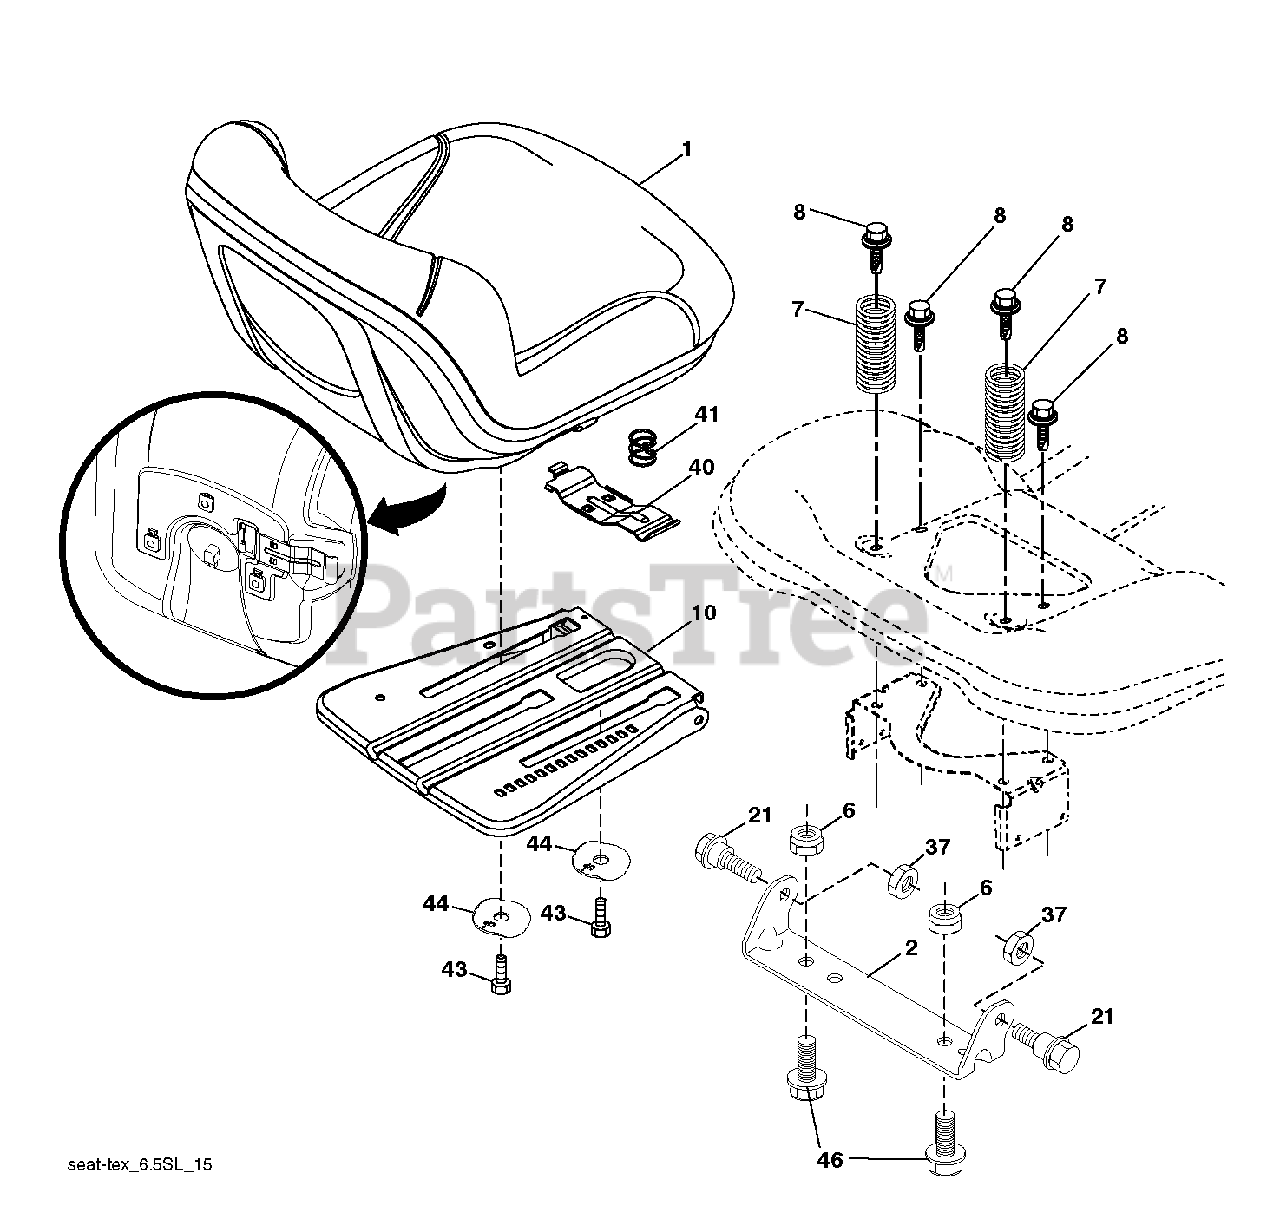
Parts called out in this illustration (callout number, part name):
1	SEAT.TH150.MS498.GRY.HUSQ.TEX
2	BRKT.PIVOT.FENDER
6	NUT
7	SPRING.COMPRESS.SEAT.
8	BOLT, 5/16-18 X 1 3/4
10	Seat Slide Plate, Pnt
21	BOLT.5/16-18X5/8.SHOULDER
37	NUT.71038.31-18.HEX.NYLOCK
40	HANDLE.SLIDE.SEAT.TEX.BLACK
41	SPRING.LATCH.SEAT.TEX
44	Winged Washer, 38Id 1
46	BOLT.3/8-16X1;1.25OD.WSHR.SEMS
